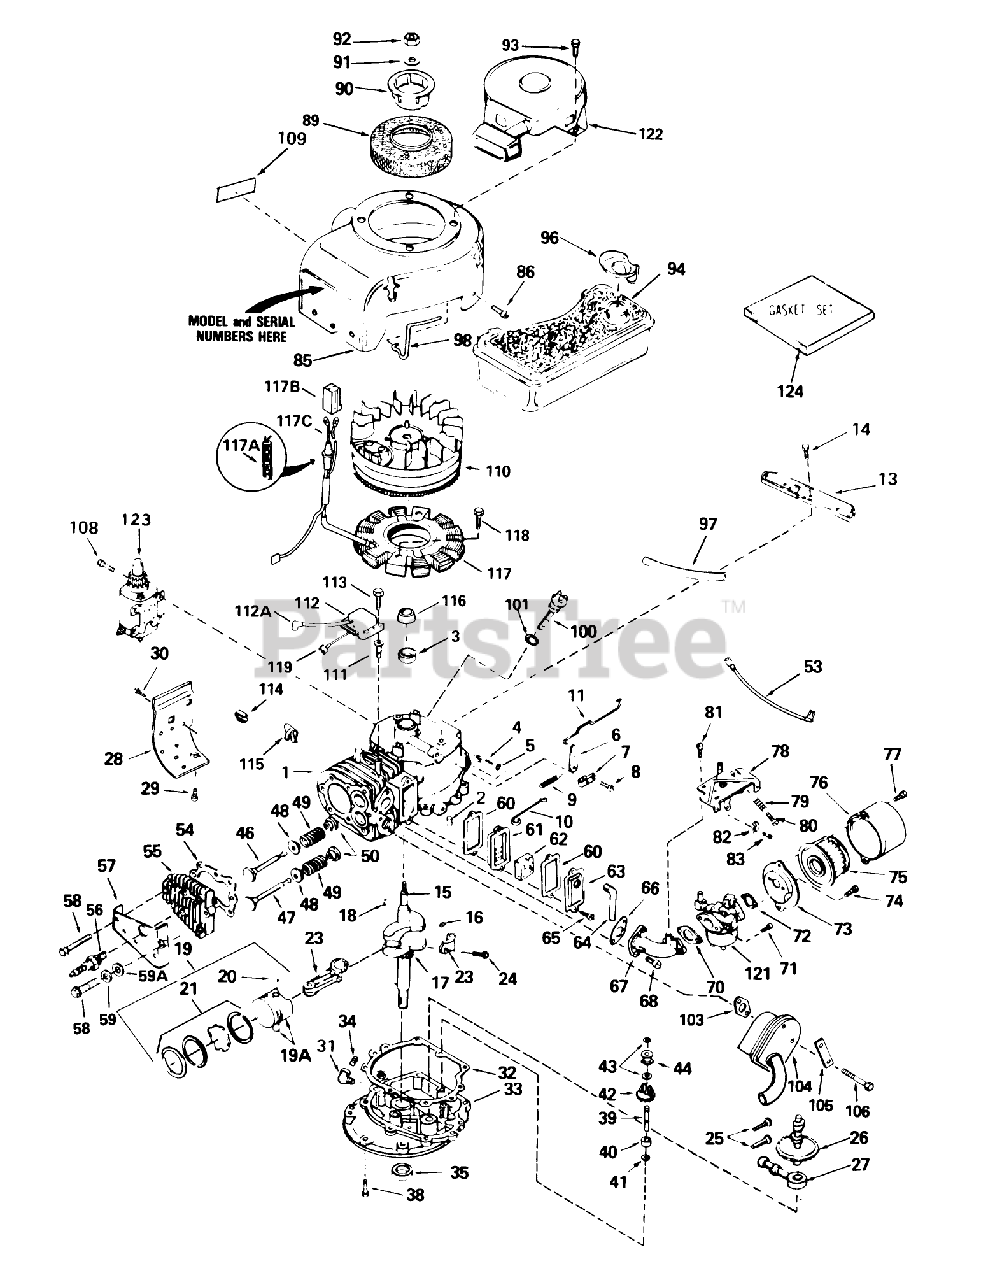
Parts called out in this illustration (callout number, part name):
1	Cylinder Assy., (Incl. Ref. #2, 3, 100 101)
2	Pin-Dowel
3	Oil Seal
4	Rod, Governor (Incl. Nos. 146)
5	Washer-Flat
6	Lever-Governor
7	Clamp-Lever, Governor
8	Screw
9	Spring Governor
10	Link Governor Spring
11	Link Governor
13	Bracket-Blower Housing
14	Screw (1/4-20x19/32)
15	Crankshaft Assy. (Incl. Ref. #16 17)
16	Pin, Groove
17	Gear-Crankshaft
18	Key-Flywheel
19	Piston, Pin Ring Assy. (Std.) (Incl. Ref. #19A, 20 21)
19	Piston, Pin Ring Assy. (.010 oversize) (Incl. Ref. #19A, 20 21 )
19	Piston, Pin Ring Assy. (.020 oversize) (Incl. Ref. #19A, 20 21)
19A	Piston Pin Assy. (Std.) (Incl. Ref. #20)
19A	Piston Pin Assy. (.010 oversize) (Incl. Ref. #20)
19A	Piston Pin Assy-. (.020 oversize) (Incl. Ref. #20)
21	ORing
21	Ring Set (.010" OS)
21	Ring Set (.020" OS)
23	Rod Assy., Connecting (Incl. Nos. 10 18)
24	Bolt-Connecting Rod
25	Lifter-Valve
26	Screw
27	Pump, Oil
28	Extension-Blower Hsng.
29	Screw
30	Screw
31	Street Elbow (90 degrees) (Can be purchased locally)
32	Gasket-Cover, Cylinder
33	Flange Assy., Mounting (Incl. Ref. #34 thru 37 39)
34	Plug-Drain, Oil (SQH 1/4-18)
35	Seal-Oil
38	Screw (1/4-20 x 1-1/4)
39	Shaft, Governor
40	Spacer Assy. Governor (Incl. Ref. #41)
41	Washer-Flat
42	Governor Gear ASM
43	Ring-Retaining
44	Spool-Governor
46	Valve, Intake (Standard)(Incl. No. 9)
46	Valve, Intake (1/32" oversize)(Incl. No. 9)
47	Valve, Exhaust (Standard)(Incl. No. 9)
47	Valve, Exhaust (1/32" oversize)(Incl. No. 9)
48	Cap-Spring, Valve
49	Spring-Valve
50	Keeper-Spring, Valve
53	Wire-Ground
54	Gasket-Cylinder Head
55	CYLINDER HEAD
56	Plug, Spark (Champion RCJ-8)
57	Cover-Head, Cylinder
58	Screw (5/16-18 X 2-1/2)
59	Washer-Belleville
59A	Washer-Flat
60	Gasket-Breather
61	Body-Breather
62	Element-Breather
63	Cover-Valve
64	Tube-Breather
65	Screw
66	Gasket-Intake
67	Pipe-Intake
68	Screw (T-30, 5/16-18x1-3/32)
70	Gasket
71	Screw-Hex Hd.
72	Gasket
73	Bracket
74	Screw (10-32 x 1/2)
75	Element
76	Body-Air Cleaner
77	Screw
78	Control Assy.Speed (Incl. Ref. #79 80)
79	Spring-Compression
80	Screw
81	Screw (10-24 x 9/16)
82	Conduit
83	Screw (10-32 x 3/8)
85	Housing-Blower
86	Screw
89	Screen-Starter
90	Cup-Starter
91	Washer-Belleville
93	Screw
94	Tank Assy., Fuel (Incl. No. 127)
96	Deflector-Fuel
97	Line-Fuel (8.62)
98	Clamp, Tank Holdown
100	Dipstick, Oil (Incl. No. 45)
101	Gasket
103	Gasket Exhaust
104	Muffler
105	62513 SNWTHWR W/284
106	Screw Hex Hd.
108	Screw
109	Decal-Instruction
110	Flywheel (3 Amp, with Ring Gear)
112	Solid State
112A	Cover-Spark Plug
113	Screw
114	Clip, Spring
115	51004 GIL ROTARY TI
116	Spacer-Coil
117	Coil Assembly-3 Amp D.C. (Incl. #117A, 117B 117C)
117A	Diode
117B	Connector Body
117C	Terminal-Female
118	Screw (1/4-20 x 3/4)
119	Terminal
121	Carburetor
122	tarter-Rewind
123	Tine Shaft
124	Gasket Set
